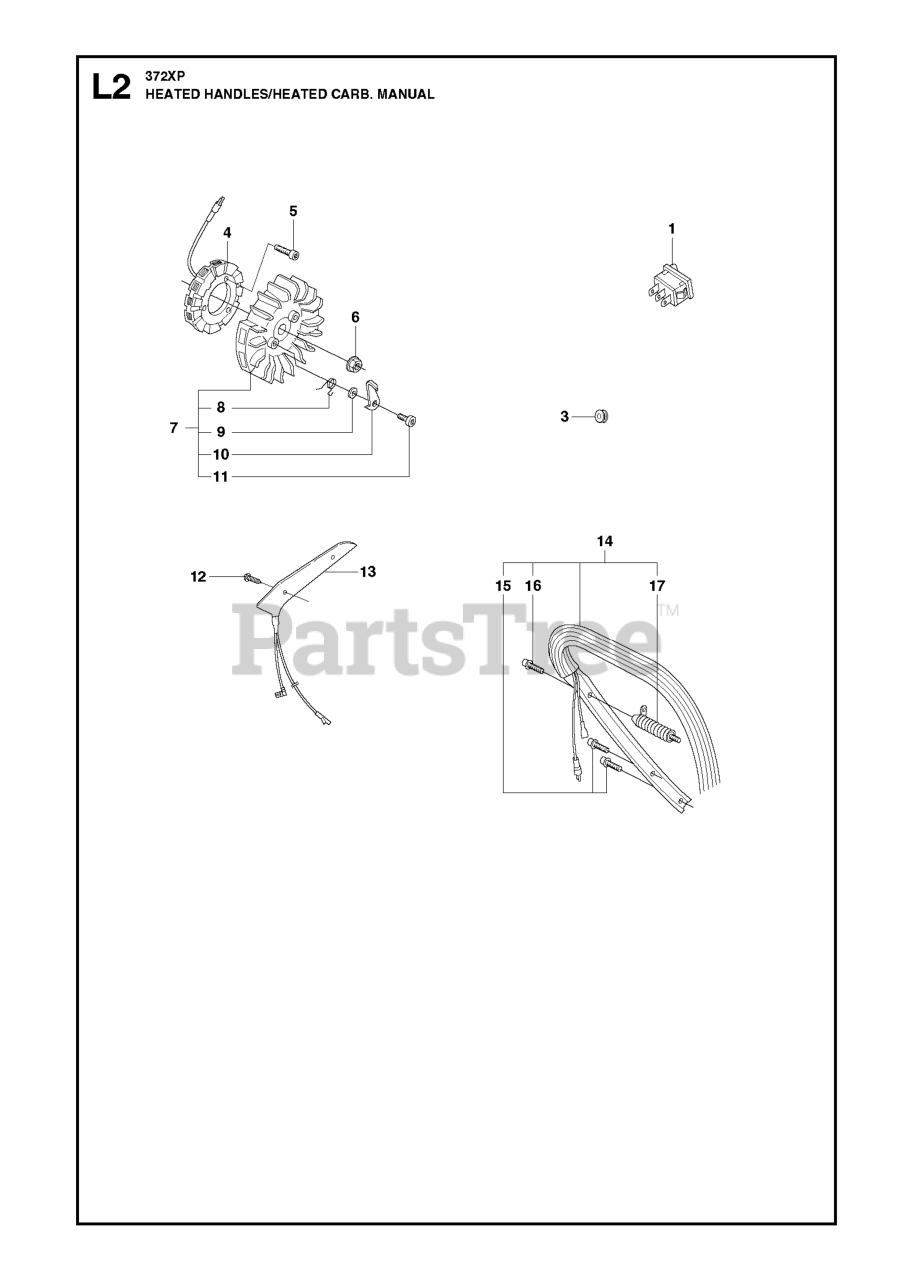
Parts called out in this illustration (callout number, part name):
6	NUT W/ WASHER
11	SCREW
14	FRONT HANDLE (G)
15	SCREW ITXSCFT PW5.5X16 T27 8.
16	SCREW ITXSCFT PW6.3X22 T27 8.
17	ANTIVIBRATION ELEMENT
